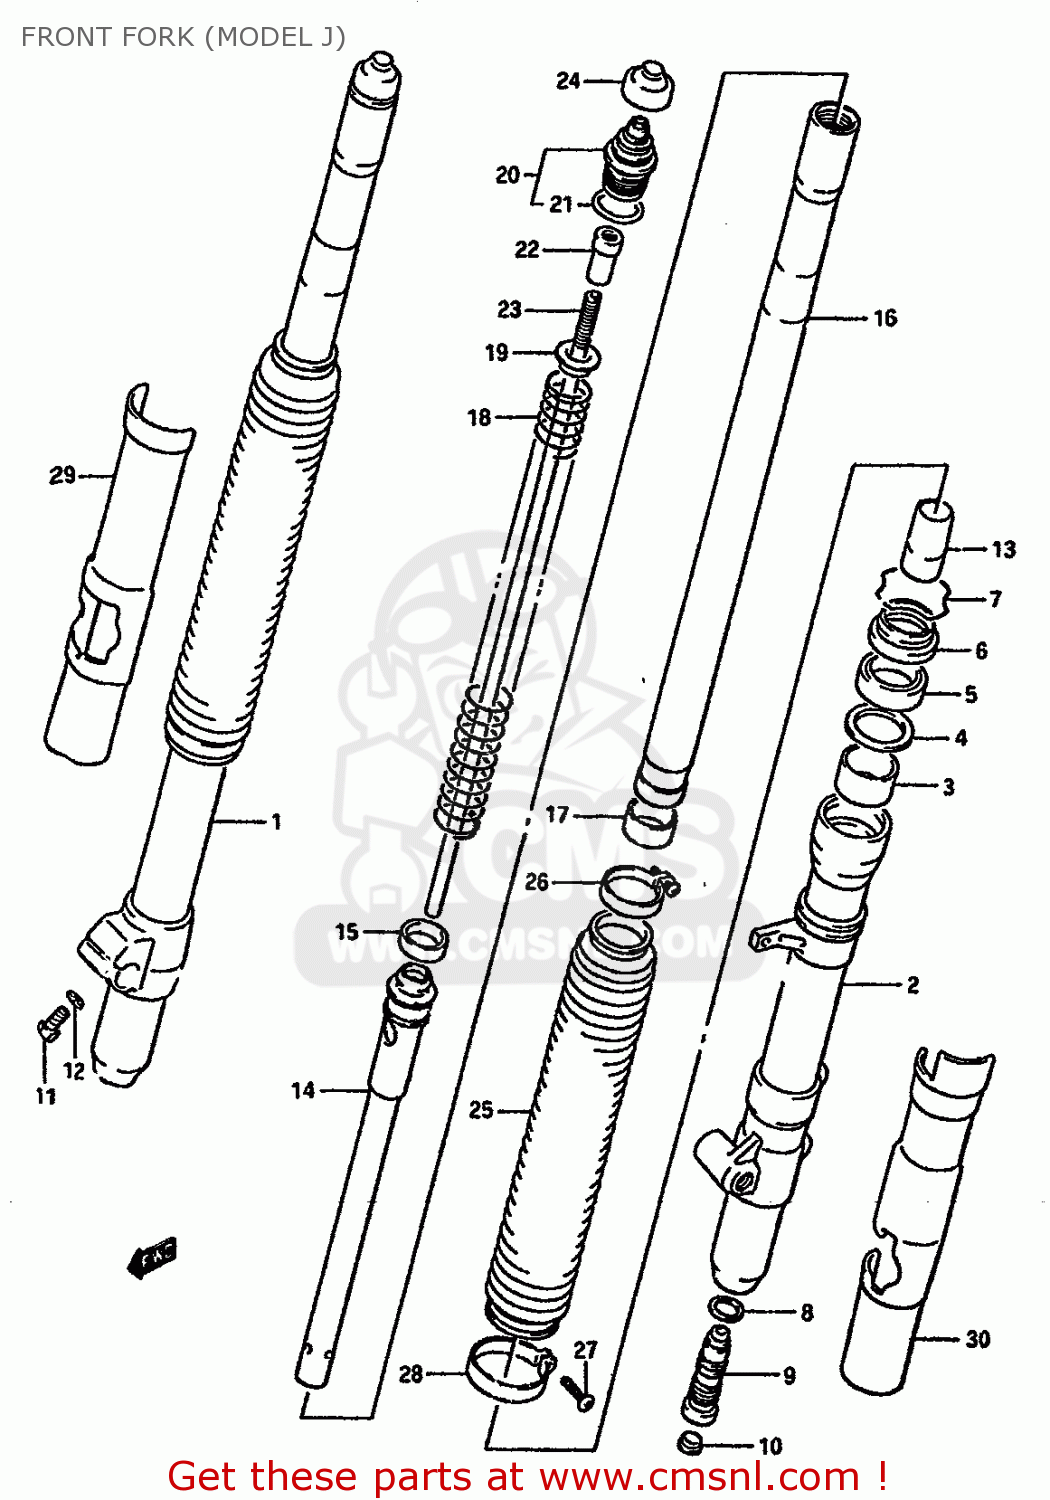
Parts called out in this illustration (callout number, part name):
1	TUBE,OUTER,RIGHT
2	TUBE,OUTER,LEFT
3	METAL,SLIDE
4	WASHER
5	OIL SEAL,FRONT FORK
6	DUST SEAL,FRONT FORK
7	RING,STOPPER
8	GASKET (NAS)
9	VALVE
10	CAP,FRONT FORK DF
11	BOLT
12	LOCK WASHER
13	PIECE,OIL LOCK
14	CYLINDER,FRONT FORK
15	RING,FRONT FORK PISTON
16	TUBE,FORK,INNER
17	PISTON
18	SPRING,FRONT FORK
19	GUIDE,FRONT FORK SPRING
20	CAP
21	O RING
22	NUT
23	ROD,PISTON
24	CAP
25	BOOT
26	BAND,BOOT UPR
27	SCREW,BAND BOOT(3.5X10)
28	BAND,BOOT LWR
29	PROTECTOR,RIGHT
30	PROTECTOR,LEFT
31	BAND,BOOT LWR
32	PROTECTOR,RIGHT
33	PROTECTOR,LEFT
